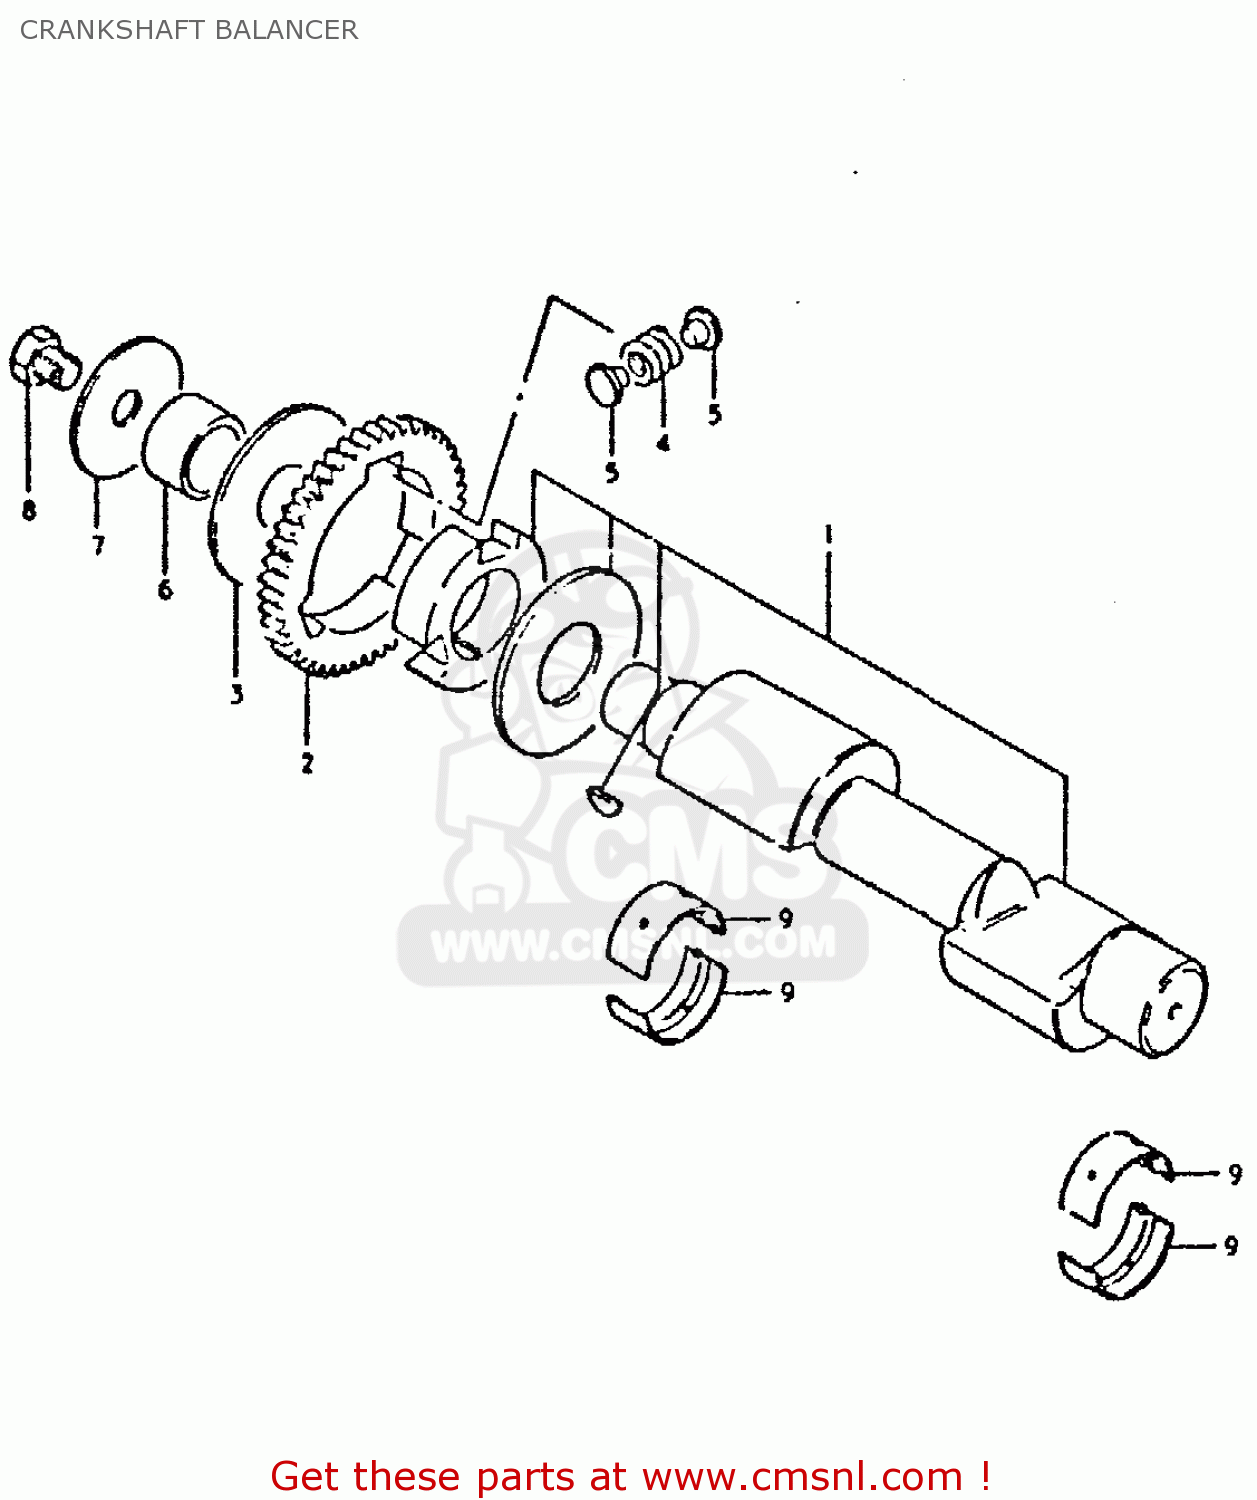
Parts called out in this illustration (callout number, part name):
1	BALANCER,CRANKSHAFT
2	GEAR,CRANK BALANCER DRIVE
3	WASHER
4	SPRING
5	PIN
6	SPACER
7	WASHER(12X50X3)
8	BOLT
9	METAL CRANKSHAFT
